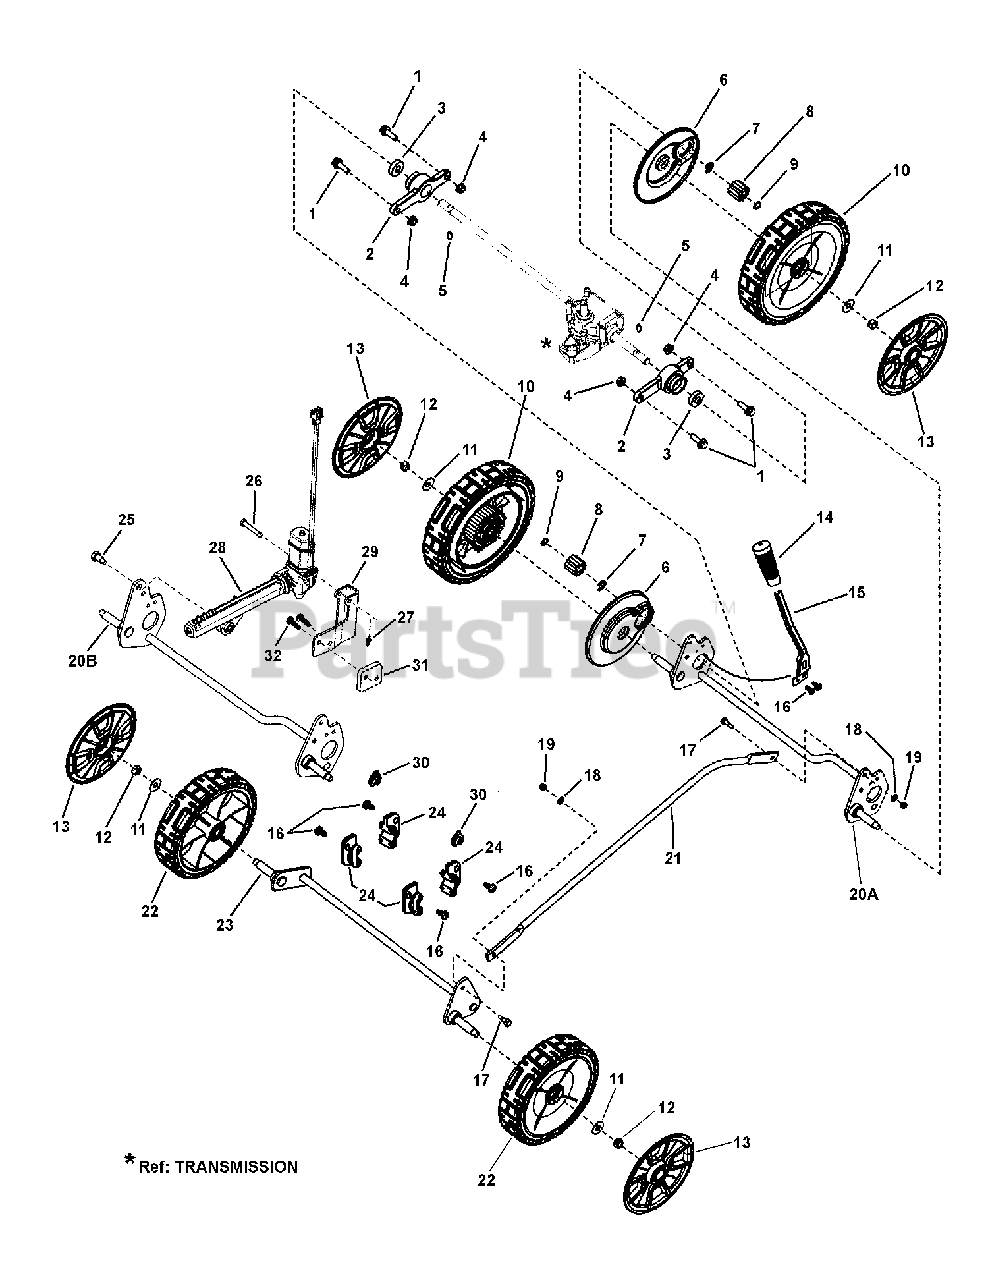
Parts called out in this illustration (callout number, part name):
1	BOLT, 5/16-18 x 1" Hex Flange Lock, GR 5, YZ
2	HOLDER, Bearing, Rear Wheel Drive
3	BALL BEARING, Axle
4	NUT, 5/16-18 Hex Flange Lock, GR 5, YZ
5	PIN, Axle
6	SHIELD, Dust, 21" WBM, RD
7	RETAINING RING, 3.92 EXT. (Waldes #5133-50 or equiv.)
8	GEAR, Pinion
9	RETAINING RING, .452-.463 ID (Waldes #5100-50 or equiv.)
10	ASSEMBLY, Wheel, 9 x 2, Snapper Tread w/Ext Gear
11	WASHER, 1" OD x .387 ID, Flat
12	NUT, 3/8-16 Hex Center Lock, YZ
13	HUBCAP, 8" & 9" Wheel Spoked-Snapper Cool Gray
14	GRIP, Height-Of-Cut
15	LEVER, Spring, Height-Of-Cut
16	SCREW, 1/4-20 x .550 Pan Head Self-Tap (Torx)
17	SHOULDER BOLT, #10-24
18	WASHER, .219 x .500 x .049 Flat
19	NUT, #10-24 UNC-2B Nyloc
20A	WELDMENT, Rear Crossbar, RWD
20B	WELDMENT, Rear Crossbar, EHOC, RWD
21	ROD, Lifter Link, WBM
22	ASSEMBLY, Wheel, 8 x 2 Idle, Snapper Tread Snapper Charcoal Gray
23	WELDMENT, Front Axle
24	BUSHING, Bearing, RWD
25	SHOULDER BOLT, 3/8 Dia. (1/4-20 threads)
26	PIN, 1/4 x 1.25" Clevis
27	PIN, 1/4" Cotter, Self-Locking
28	MOTOR, Electric, HOC
29	BRACKET, Electric Motor
30	SPACER, Shaft, 1/2"
31	PLATE, Spacer, EHOC
32	SCREW, 1/4-20 x 3/4" Pan Head Self-Tap (Torx)
